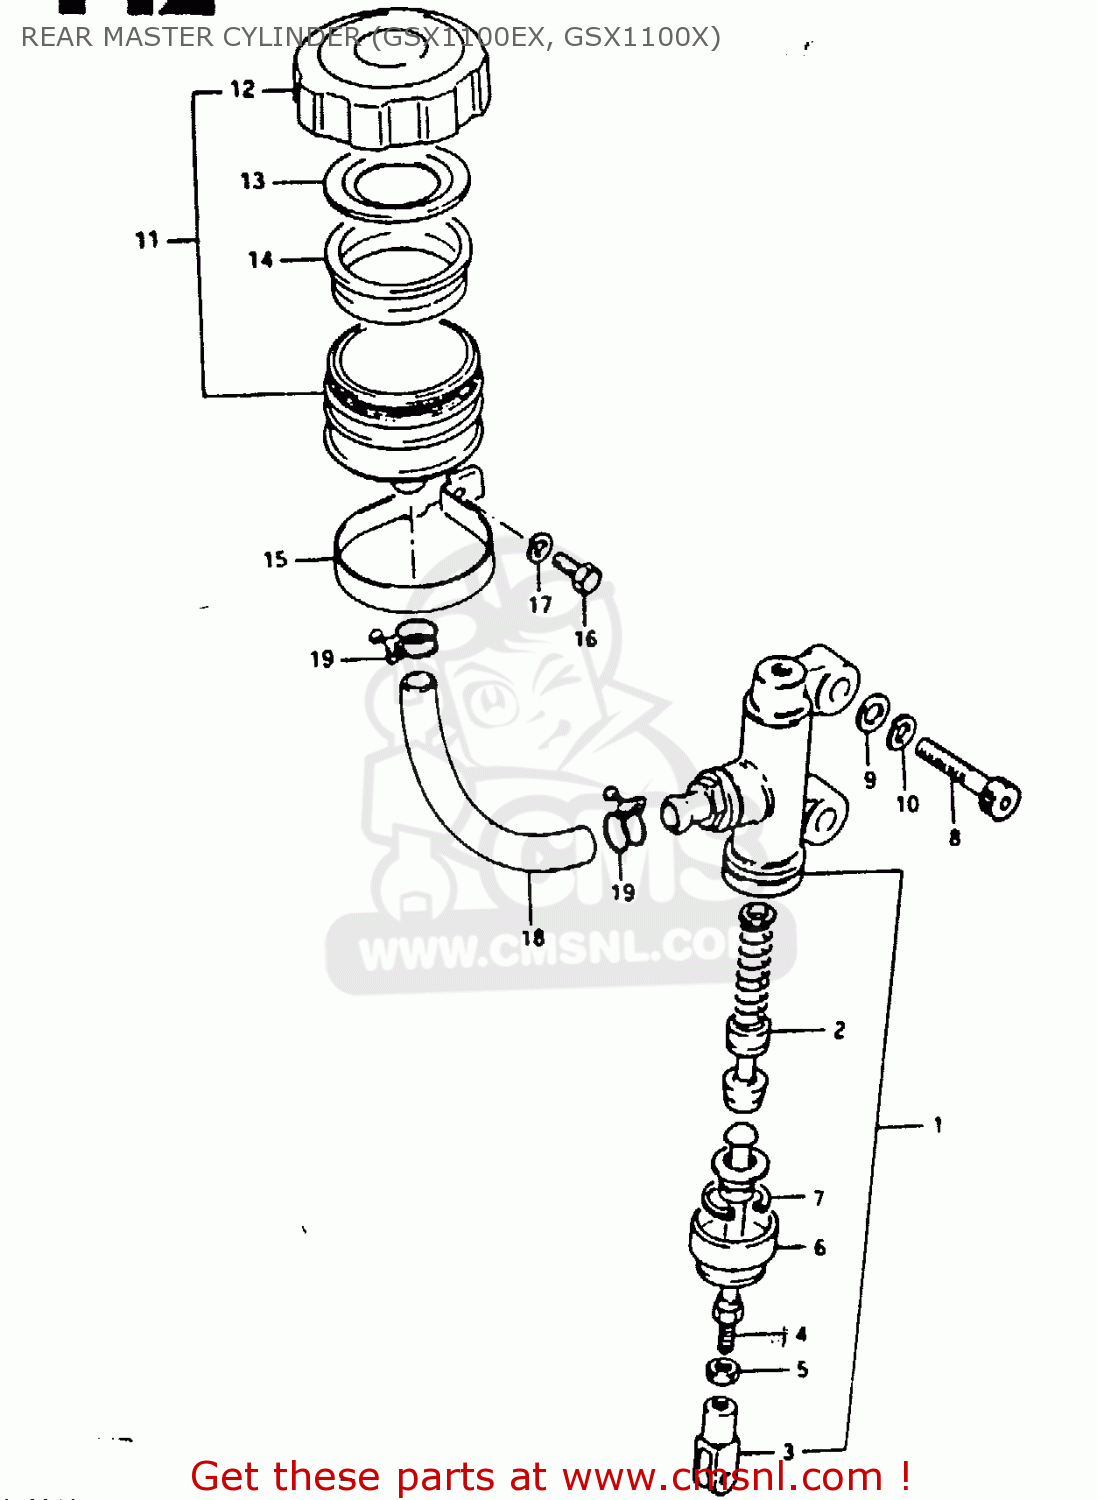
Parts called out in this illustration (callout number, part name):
1	CYLINDER ASSEMBLY,REAR MASTER
2	PISTON/CUP SET
3	YOKE
4	ROD,PUSH
5	NUT
6	BOOT
7	CIRCLIP
8	BOLT (8X30)
9	WASHER
10	LOCK WASHER
11	TANK ASSEMBLY,RESERVOIR
12	CAP
13	PLATE,DIAPHRAGM
14	DIAPHRAGM
15	CLAMP
16	BOLT, UPPER
17	LOCK WASHER
18	HOSE,RESERVOIR TANK
19	CLAMP
